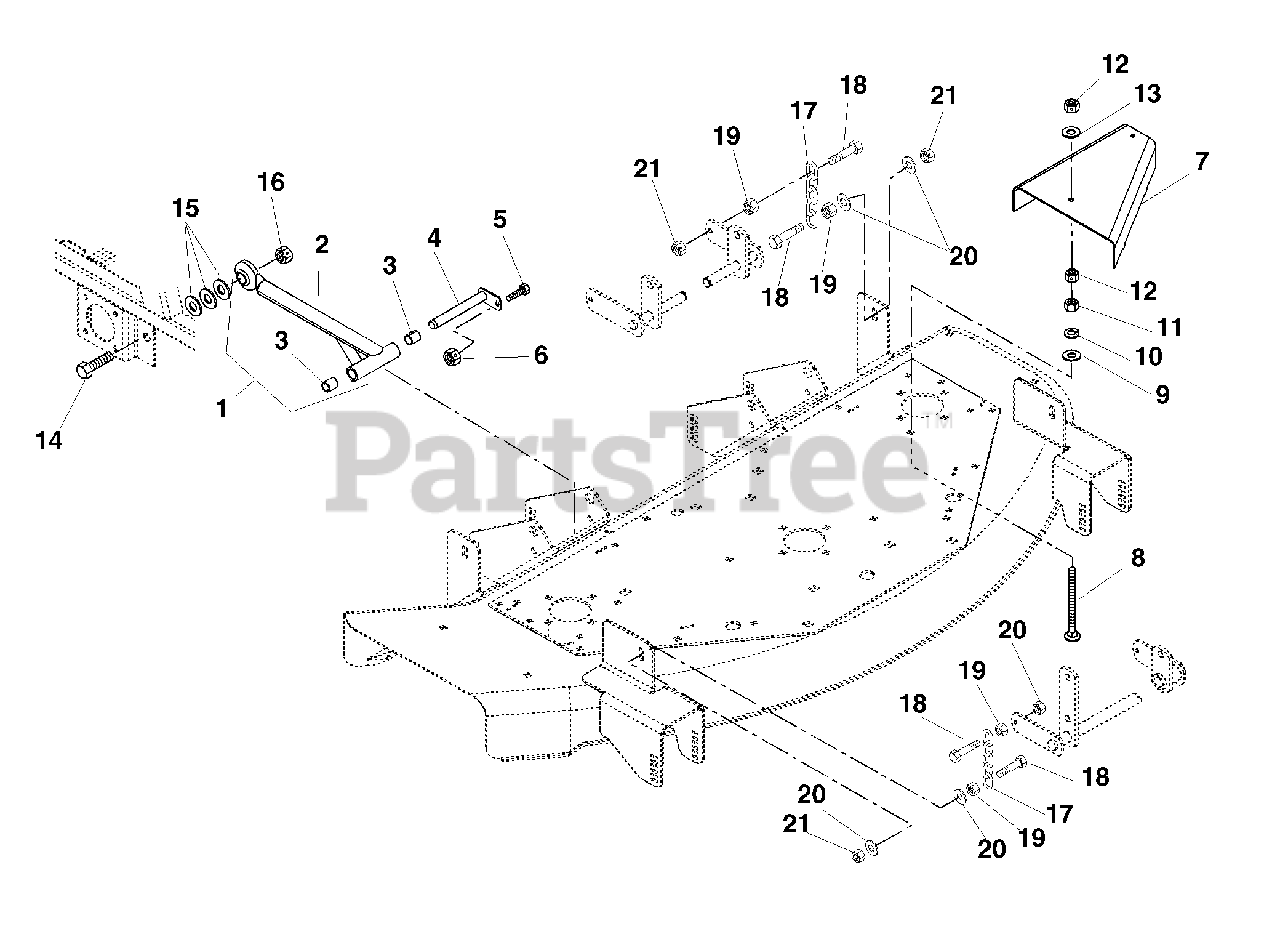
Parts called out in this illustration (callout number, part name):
1	Assembly, Mower Mounting Arm
2	Weldment-Mower Mounting Arm
3	Bearing .75 x .875 x 1.00
4	Weldment, Mower Mounting Pin
5	Bolt-Hex .38-16 x .75 Grade 5
6	Nut-Locking-Center .38-16
7	Guard, Pulley Right Hand
7	Guard, Pulley Left Hand
8	Bolt-Round Head Square Neck .31-18 x 3.50
9	Washer-Flat-Steel .344 x .688 x .065
10	Washer-Locking .31 x .078
11	Nut-Hex .31-18
12	Nut-Locking-Center .31-18
13	Washer-Flat-Steel .438 x 1.00 x.083
14	Bolt-Hex .875-9 x 2.75 Grade 5
15	Washer-Flat-Steel .875 x 1.500 x .1196
16	Nut-Locking-Center .875-9
17	Chain, Link
18	Bolt-Hex .38-16 x 1.50 Grade 5
19	Nut-Hex .38-16
20	Washer-Flat-Steel .406 x .812 x .065
21	Nut-Locking-Center .38-16
